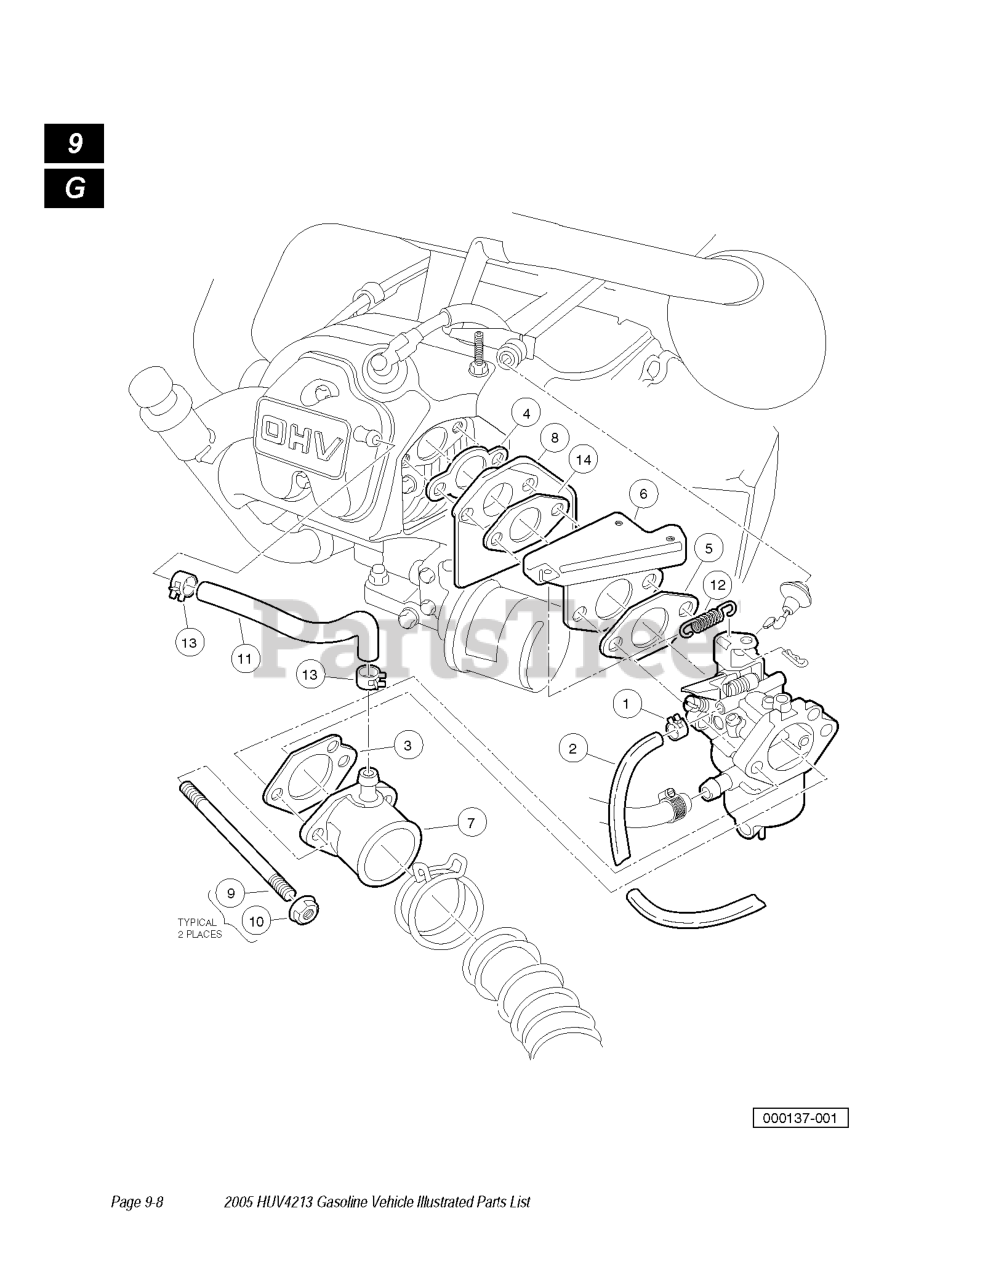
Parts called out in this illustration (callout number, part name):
2	FUEL LINE
3	GASKET, CARB TO INTAKE MANIFOL
4	GASKET, ENGINE TO INSULATOR
5	GASKET, SPRG BRKT TO CARB OHV
6	BRACKET, THROTTLE SPRG RETURN
7	PIPE, INTAKE MANIFOLD
8	INSULATOR, CARBURETOR
9	STUD, M6-1.00 2-ENDED
11	TUBE, CRANKCASE VENT
12	SPRING, THROTTLE RETURN
14	GASKET, INSULATOR TO BRACKET
